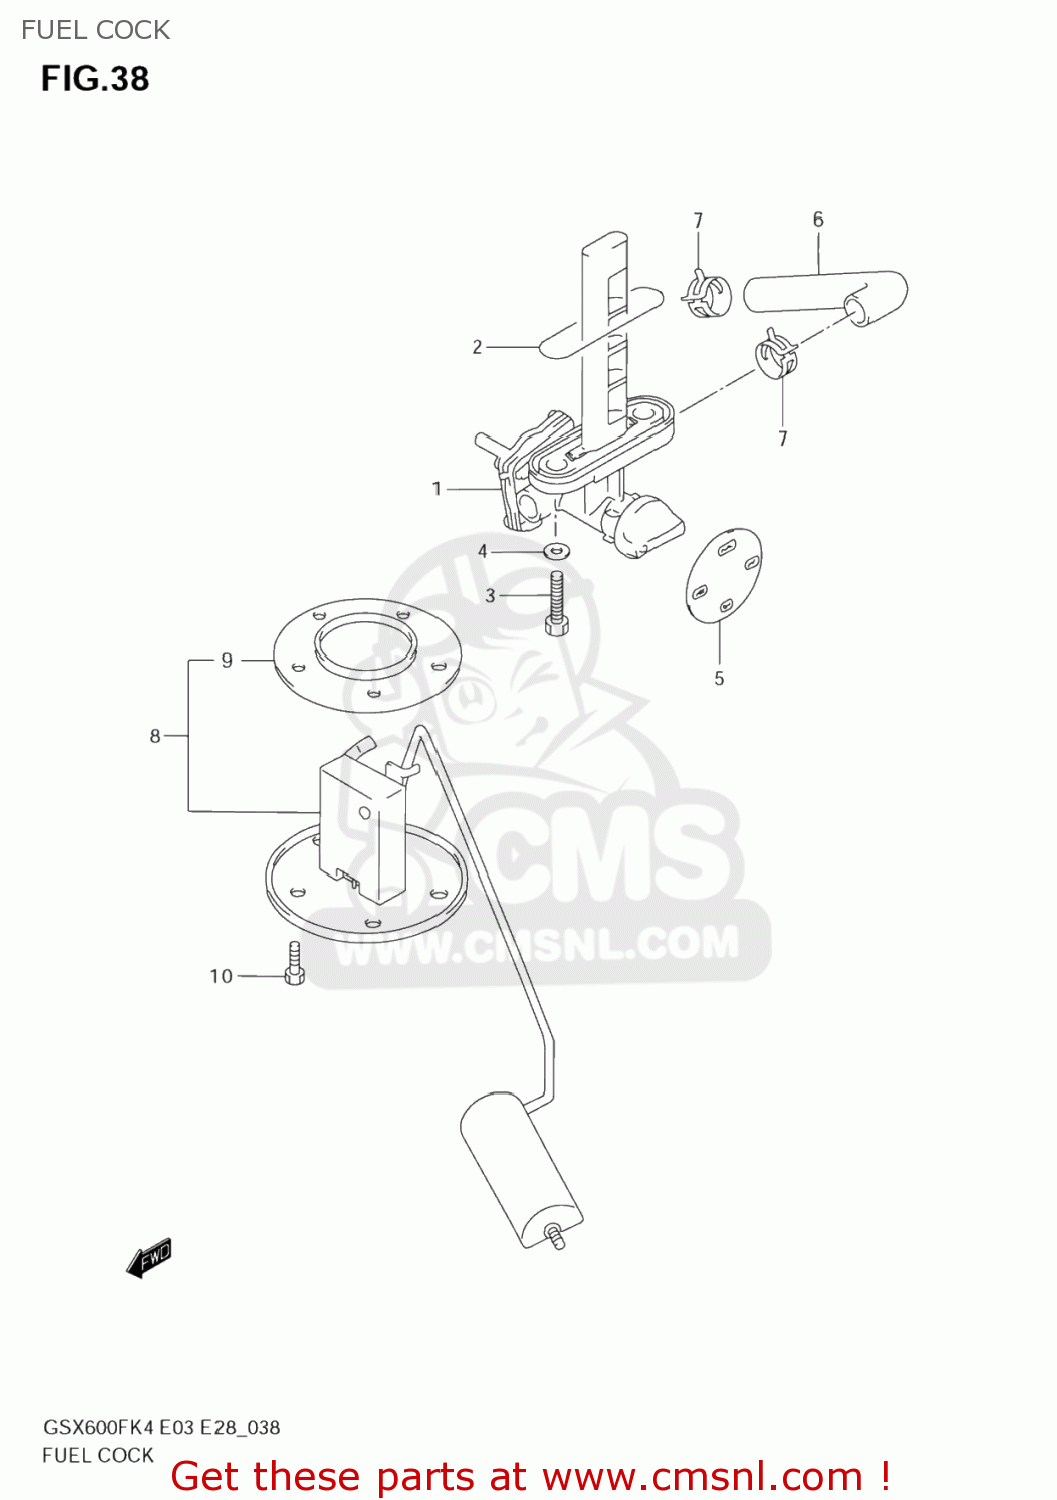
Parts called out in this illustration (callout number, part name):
1	COCK ASSEMBLY,FUEL
2	O RING
3	BOLT(6X20)
4	GASKET(6.4X11.5X0.8) (NAS)
5	LABEL,FUEL COCK(GRAY)
6	HOSE,FUEL ON
7	CLIP
8	GAUGE ASSY,FUEL LEVEL SENDER
9	GASKET,FUEL LEVEL GAUGE (NAS)
10	BOLT 5X10
